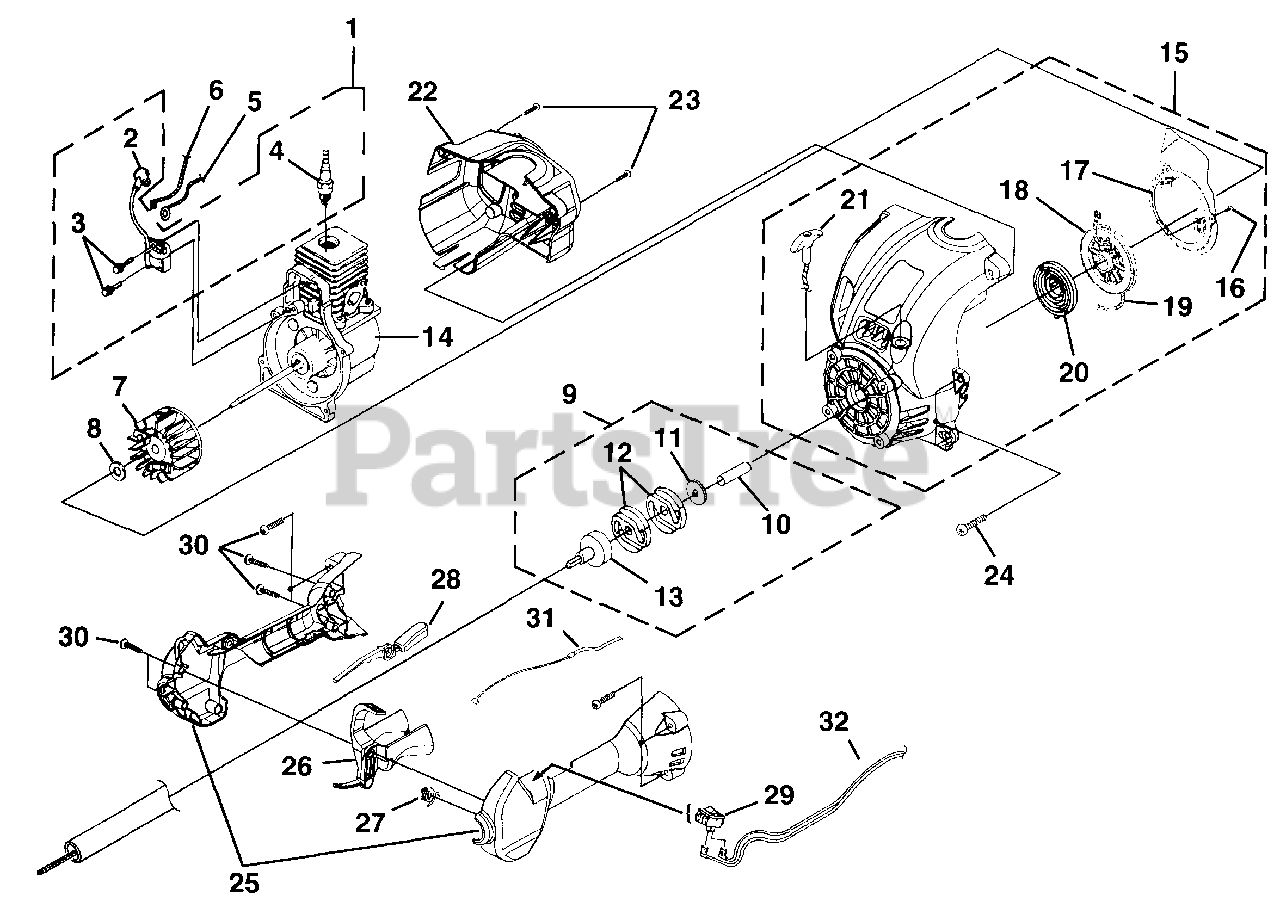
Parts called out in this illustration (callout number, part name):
1	IGNITION KIT
2	TERMINAL & COVER
3	SCREW-Taptite (8-32 X 1")
4	SPARK PLUG (RDJ-7Y)
5	LEAD-Electrical
6	LEAD-Electrical
7	ROTOR KIT
8	WASHER-Flat
9	CLUTCH AND DRUM KIT
10	SPACER
11	WASHER-Flat
13	CONNECTOR AND DRUM
14	SHORT BLOCK
15	COMPLETE STARTER ASSEMBLY
16	SCREW-Thread Form (8-16 X 1/2")
17	BAFFLE-Air
18	PULLEY-Starter
19	ROPE-Starter (42")
20	SPRING & CONTAINER
21	GRIP-Starter (Yellow)
22	HOUSING-Rear Kit
23	SCREW-Plastite (10-14 X 3/4")
24	SCREW-Taptite (10-24 X 3/4")
25	CONTROL HANDLE ASSY.
26	TRIGGER-Throttle
27	SPRING
28	THROTTLE INTERLOCK
29	SWITCH
30	SCREW-Taptite (10-14 X 1")
31	CABLE-Throttle
32	LEAD-Electrical
